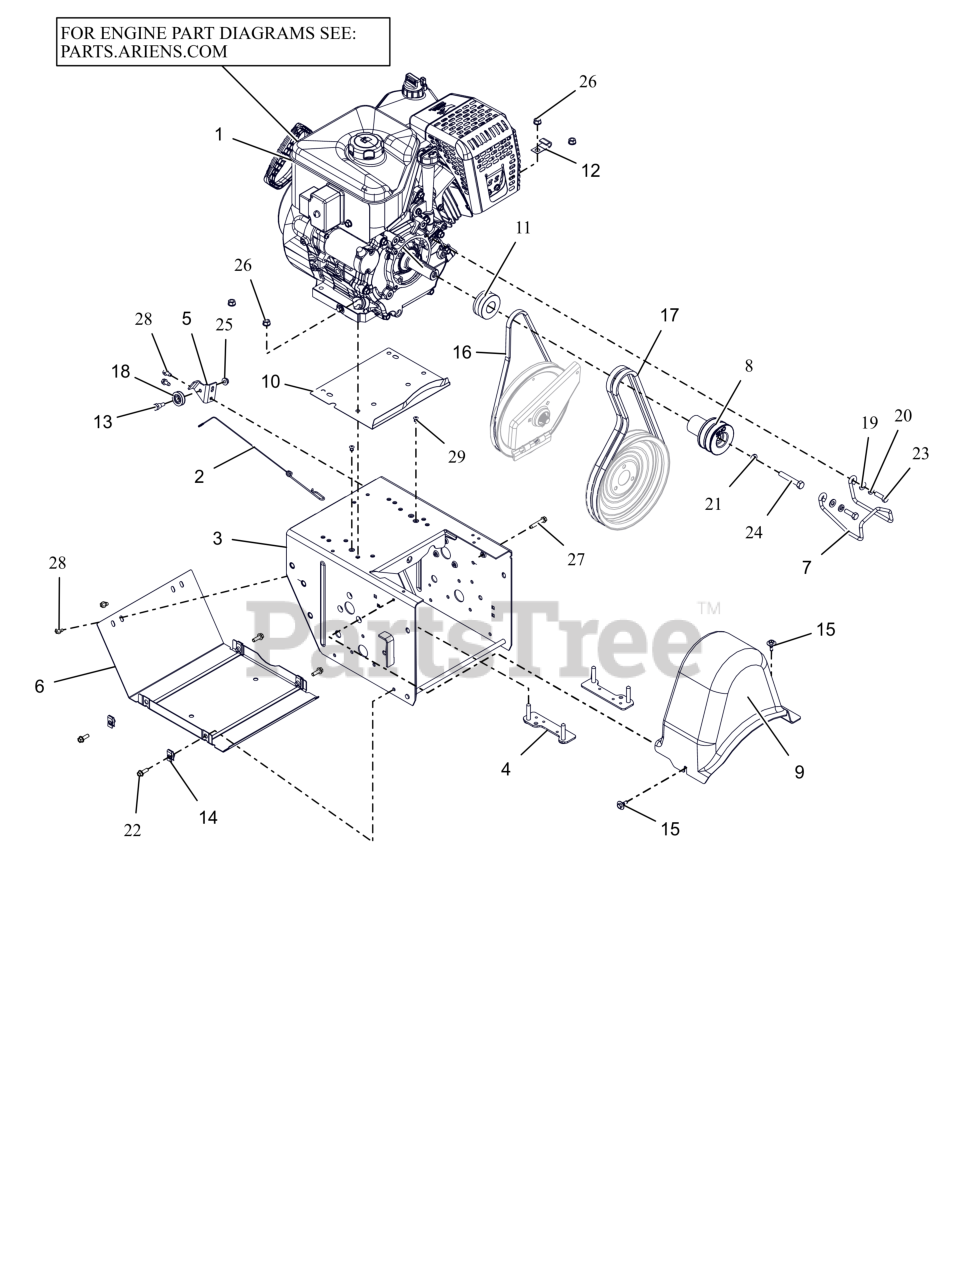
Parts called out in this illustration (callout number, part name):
1	ENGINE, AX420 GEN 3 120V/60W
2	CABLE, LOWER TRACTION,SS & PRO
3	FRAME, MAIN - PRO (WELDMENT)
4	STRAP, BOLT-LARGE
5	BRACKET, CABLE PULLEY
6	COVER, BOTTOM
7	FINGER, BELT
8	SHEAVE,ATTACHMENT-SHO 2 GRV
9	COVER, BELT-LARGE
10	BAFFLE, WATER - LARGE BLOCK
11	SHEAVE, TRACTION (KEYLESS)
12	J-CLAMP
13	BOLT, SHLDR -.375 X .375 X .25-20
14	NUT-RTNR .25-20X.56
15	SCR-TAP .25-20X.5 CAPTIVE
16	V-BELT, 3L-WRAPPED
17	V-BELT, HA-RAW EDGE (SET)
18	PULLEY, CABLE
19	WSHR,FLT .344X.688X.065 ZCC
20	WSHR, LK-HVY .312X.097 ZCC
21	WSHR,LK-REG .375X.094 ZCC
22	BLT, HWH .25-20X.75 G5 ZCC
23	BLT, HEX 0.3125-24X1 G5 ZCC
24	BLT, HEX .38-24X2.25 G5 ZCC
25	NUT-LK-TOP-FLG .250-20 GF ZCC
26	NUT,LK-CTR-FLG .31-18 GF ZCC
27	SCR,TAP .25-20X1.50 HWH TR ZCC
28	SCR-TAP .25-20X.50 HWH ZCC
29	RVT, POP .1875 ZCC
